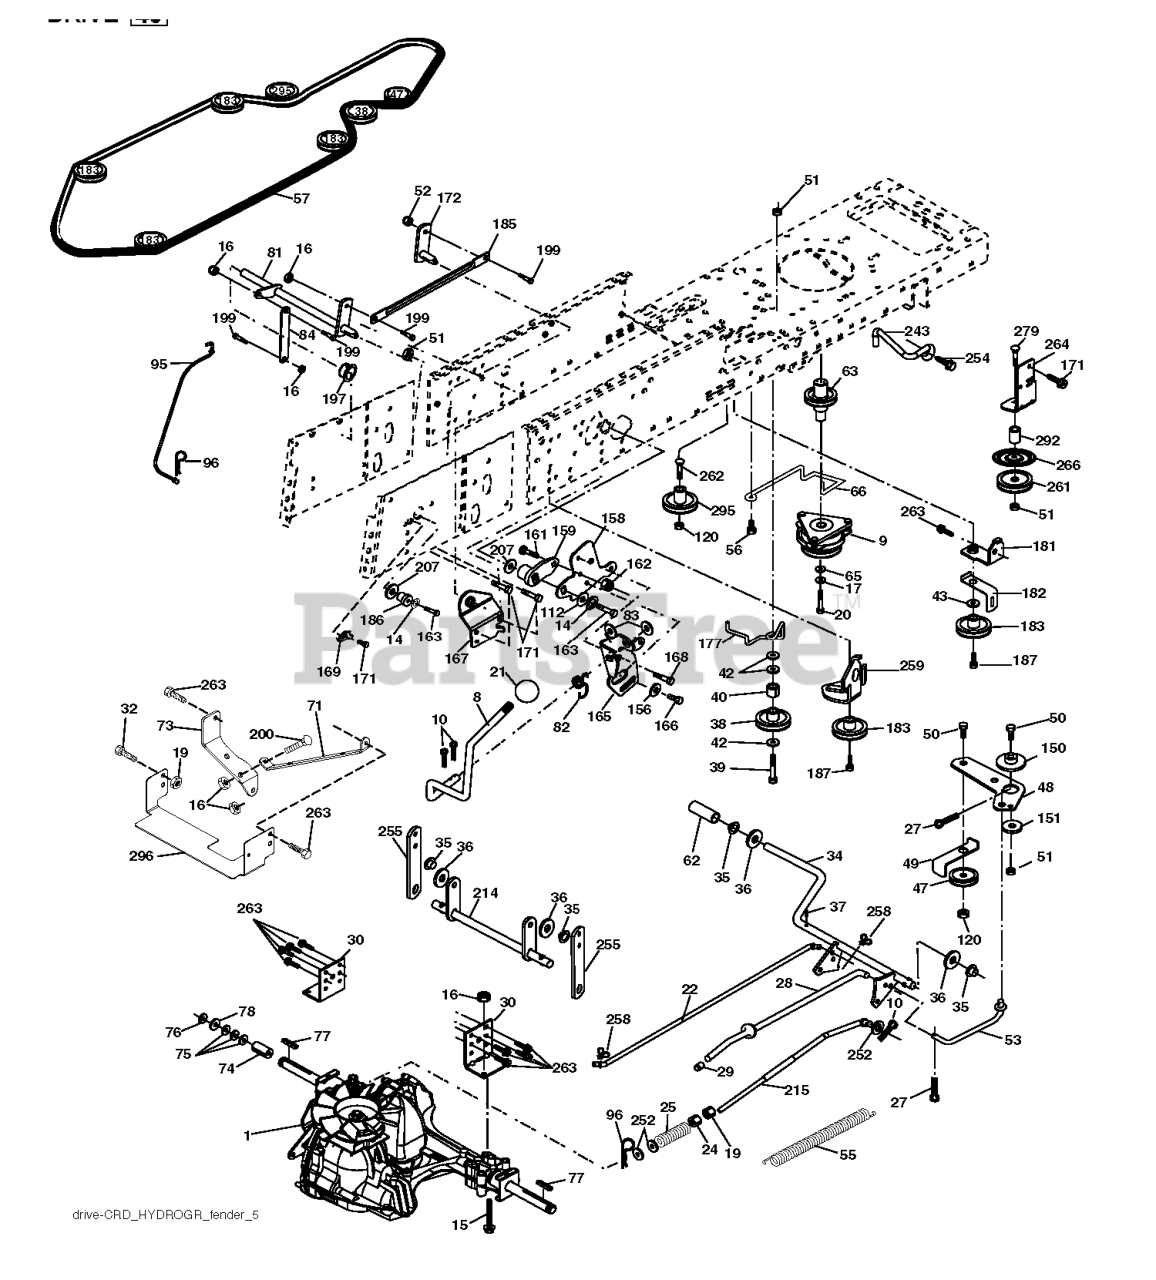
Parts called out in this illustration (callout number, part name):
8	ROD SHIFT FENDER ADJUST LT
9	CLUTCH.ELECTRIC.OGURA.EURO.
10	PIN COTTER
14	LOCKWASHER
15	BOLT HEX 5/16-18 GR 5
16	NUT.71038.31-18.HEX.NYLOCK
19	NUT
20	BOLT HEX 7/16-20X4-1/4"
21	KNOB.DUCKHEAD.1/2
22	ROD
24	NUT
25	SPRING BRAKE ROD
27	COTTER PIN
28	ROD, PARKING BRAKE
29	CAP
30	BRKT, TRNSXLE MNT 20"
32	BOLT
34	SHAFT, FOOT PEDAL
35	BEARING.NYLON
37	DRIVE PIN
38	PULLEY.FLAT
42	WASHER
47	IDLER PULLEY
48	BELLCRANK, CLUTCH
49	RETAIN BELT
50	BOLT.3/8-16X1.50
52	LOCKNUT
53	LINK.CLUTCH.7.66.2005
55	SPRING, RETURN LT
56	SCREW.3/8-16
57	V-BELT 113"
62	PEDAL COVER T
63	PULLEY.ENGINE.CVX.LT
65	LOCKWASHER
66	KEEPER BELT ENGINE
71	STRAP TORQUE LH HYDRO
73	STRAP TORQUE RH HYDRO
74	SPACER AXLE
77	SQUARE KEY
81	ASM.CROSS.SHAFT.REAR.CRD.0510
82	SHIFT SPRING
83	WASHER
84	LINK.PNT.TRANSAXLE.0510.CRD
95	LINK
96	RETAINER M
120	NUT LOCK FLG 3/8-16 UNC
150	BUSHING.BELLCRANK.GRD.DR
151	WASHER 12/32X2X10GA
156	WASHER.SRRTD.5/16
158	BRACKET
159	RB HUB.SHIFT
161	BOLT
162	NUT.CROWNLOCK.1/4
165	RP BRACKET
166	CAPSCREW.HXHD.FLG.5/16-18X.625
167	BRACKET.SUPT.SHIFT.CRD
168	BOLT.SHOULDER.5/16-18X
169	PLATE.FASTENING.CROSS.SHAFT
172	LINK
181	BRACKET
182	BELT GUIDE
183	PULLEY.V-IDLER.GRND.DR
185	LINK
186	HUB.TAPERED.ROUND.CRD
187	BOLT.5/16-18X1.25
197	NYLINER SNAP 5/8" ID
199	BOLT SHOULDER 5/16-18 UNC
207	WASHER NYL
214	LEVER
215	ROD
243	BRACKET, ANTI-ROTATION
252	WASHER
254	SCREW 3/8-16X1
255	SHAFT
258	CLIP RETAINER
259	BRACKET
261	FLAT IDLER PULLEY
263	SCREW, 3/8-16X3/4
266	PROTECTOR
292	SPACER
295	PULLEY IDLER COMPOSITE
